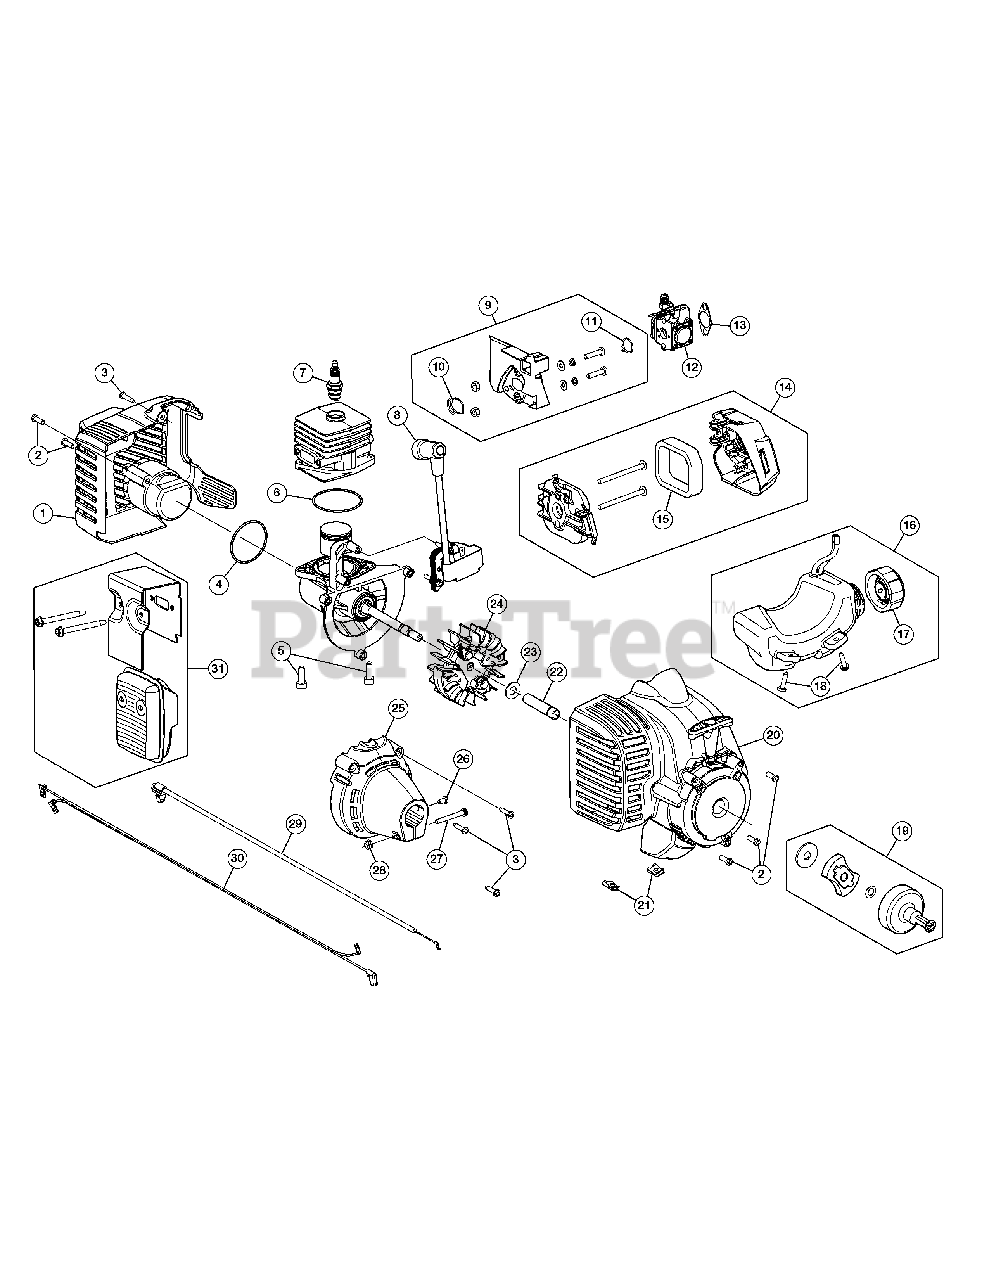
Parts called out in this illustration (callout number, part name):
1	Rear Cover Assembly (Incl. 2 & 3)
2	Housing Screw
3	Cover Screw
4	O-Ring
5	Crankcase Bolt
6	Crankcase O-Ring
7	Spark Plug
8	Module Assembly
9	Insulator Assembly (Incl. 10 & 11)
10	Insulator O-Ring
11	Carburetor O-Ring
12	Carburetor
13	Air Cleaner Gasket
14	Aircleaner Cover Assembly (Incl. 15)
15	Aircleaner Filter
16	Fuel Tank Assembly (Incl. 17 & 18)
17	Fuel Tank Cap
18	Fuel Tank Screw
19	Starter Clutch Assembly
20	Starter Housing (Incl. 2 & 21)
21	U-shaped Nut
22	Spacer
23	Washer
24	Flywheel Assembly
25	Clutch Cover (Incl. 3)
26	Anti-rotation Screw
27	Clamp Screw
28	Clamp Nut
29	Throttle Cable
30	Lead Wires
31	Muffler Assembly
